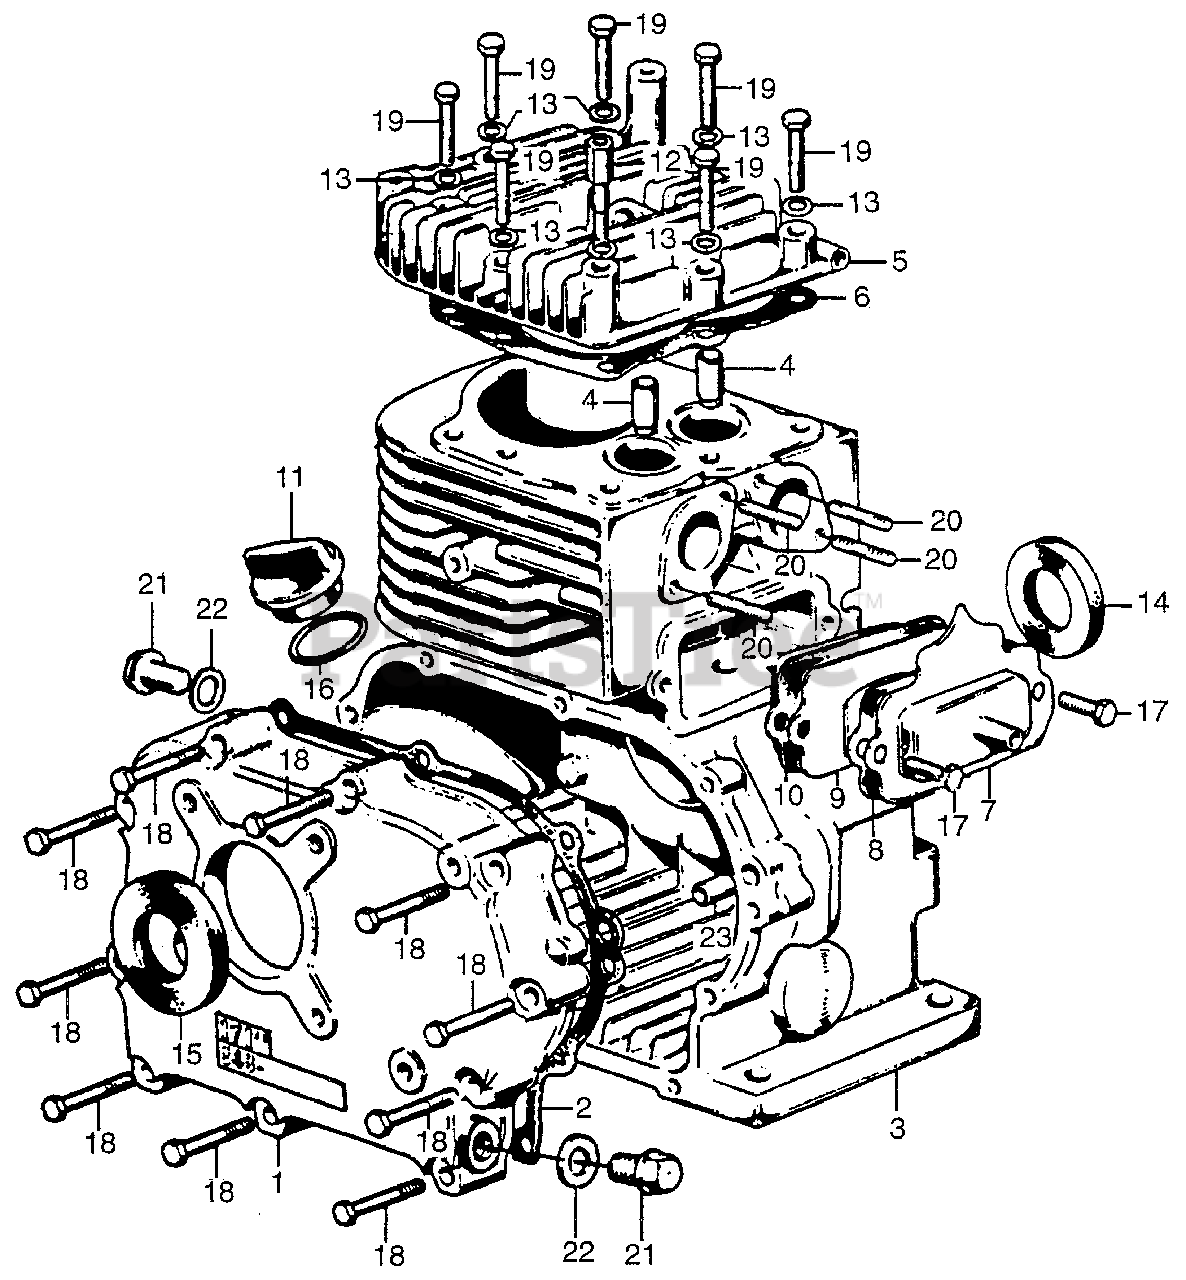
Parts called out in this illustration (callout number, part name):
1	COVER, CRANKCASE
2	GASKET, CRANKCASE (NOT AVAILABLE)
4	GUIDE, VALVE
5	CYLINDER HEAD
6	GASKET, CYLINDER HEAD (NOT AVAILABLE)
7	COVER, TAPPET
8	GASKET, TAPPET COVER
9	PLATE, BREATHER
10	BREATHER, SEPARATE (NOT AVAILABLE)
12	BOLT, CYLINDER HEAD CLAMP
13	WASHER, HEAD (8MM)
14	OIL SEAL (25X46X7) (NOT AVAILABLE)
15	OIL SEAL (30X55X7)
16	O-RING (26X2.7)
17	BOLT, HEX. (6X16)
18	BOLT, HEX. (6X32)
19	BOLT, HEX. (8X45)
20	BOLT, STUD (6X27) (NOT AVAILABLE)
21	BOLT, DRAIN PLUG (12MM)
22	WASHER, DRAIN PLUG (12MM)
23	PIN A, DOWEL (8X14)
